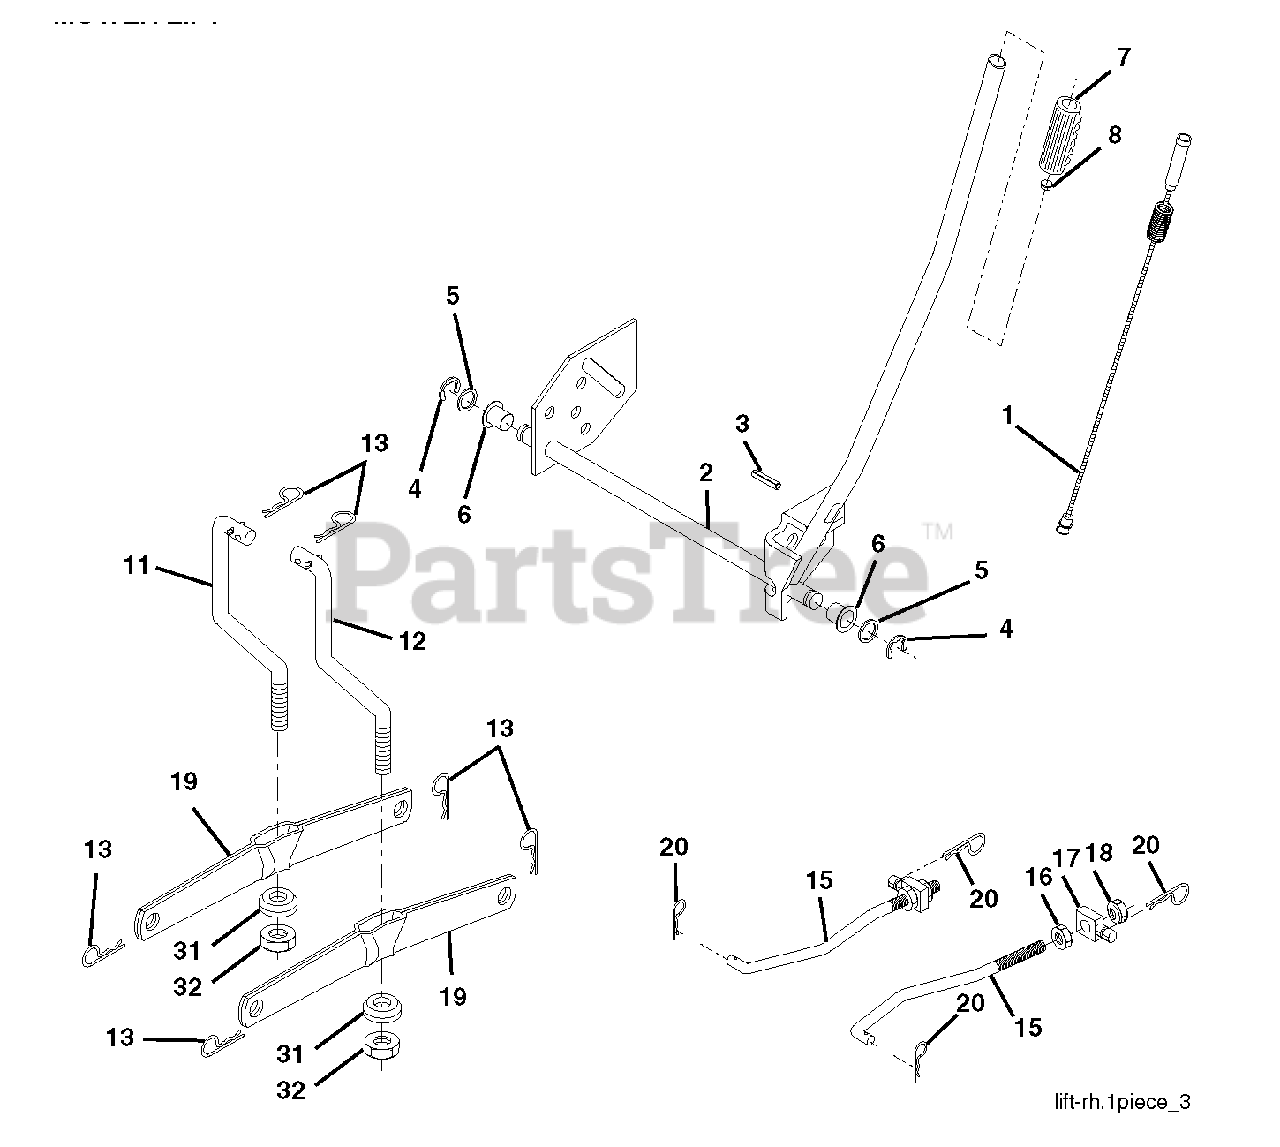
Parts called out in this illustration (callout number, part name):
1	PLUNGER.ASM.LIFT.LVR.B*SUBS/2*
2	SHAFT.ASM.LIFT.YT
3	Groove Pin, 5/16
4	RETAINING RING LT
6	BEARING.NYLON
7	GRIP
8	PLUNGER BUT KIT
11	LINK LIFT LH
12	LINK LIFT RH
13	RETAINER-SPRNG RB
15	LINK.SUSPENSION.FRONT
16	NUT
18	NUT
19	ARM.REAR.SUSPENSION
20	PIN.COTTER.7/16.BOW TI
31	BEARING.PIVOT.LIFT
32	NUT CROWNLOCK 3/8-24
